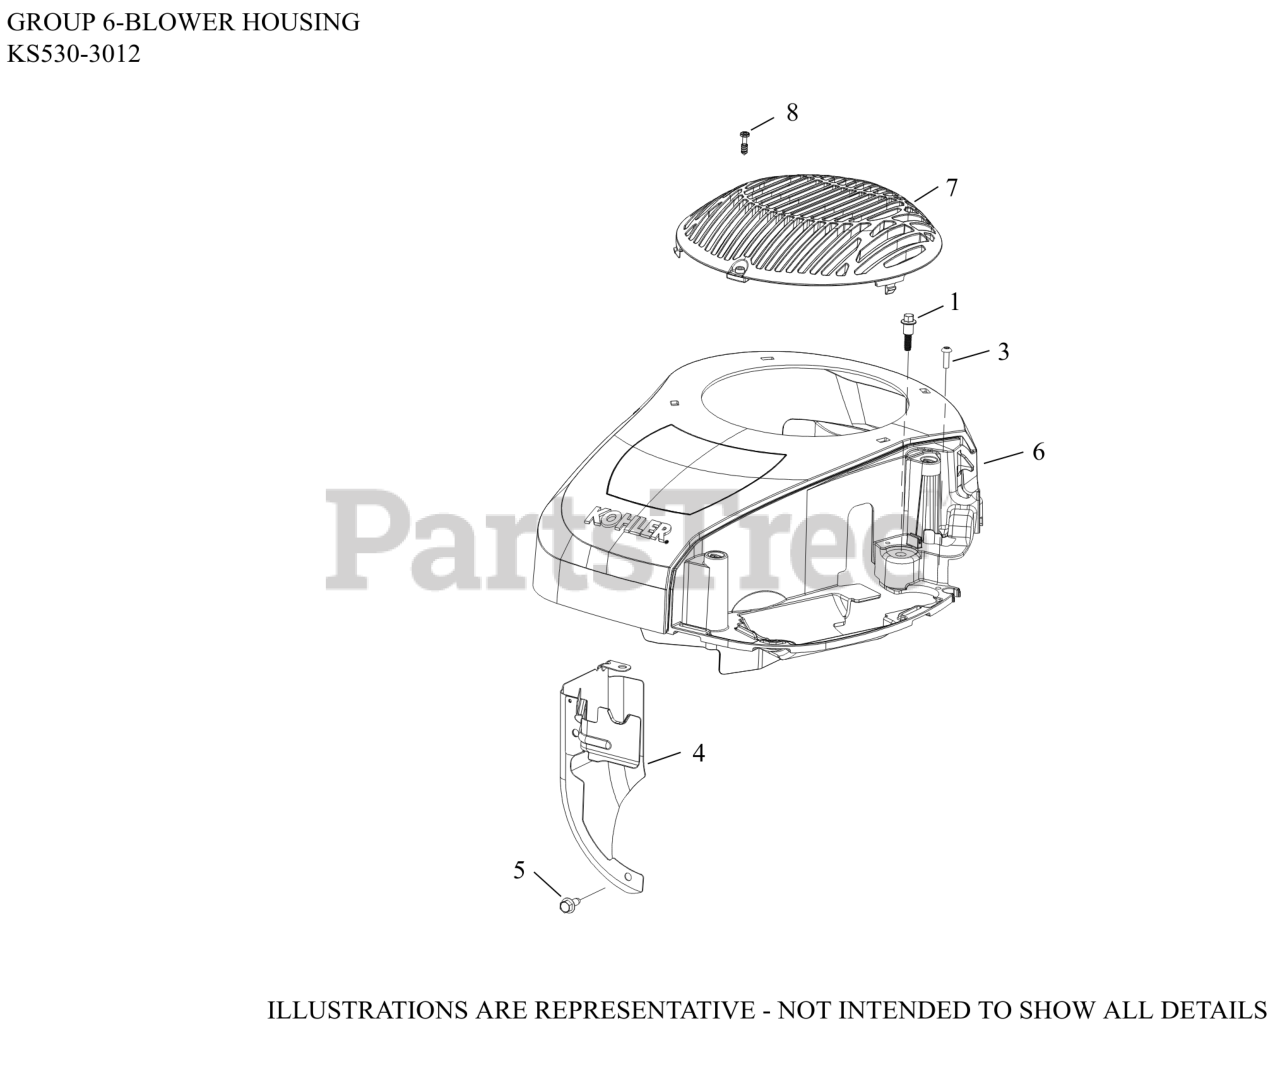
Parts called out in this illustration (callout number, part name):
1	SCREW, SHD THD FRM M6X1X26
3	SCREW, HI-LOW
4	BAFFLE, BARREL ASSY
5	SCREW, THREAD FORMING
6	KIT, BLOWER HOUSING-USE 22 027 05-S
7	GUARD, FIXED
8	SCREW, M5-2.42 (PT) THREAD
